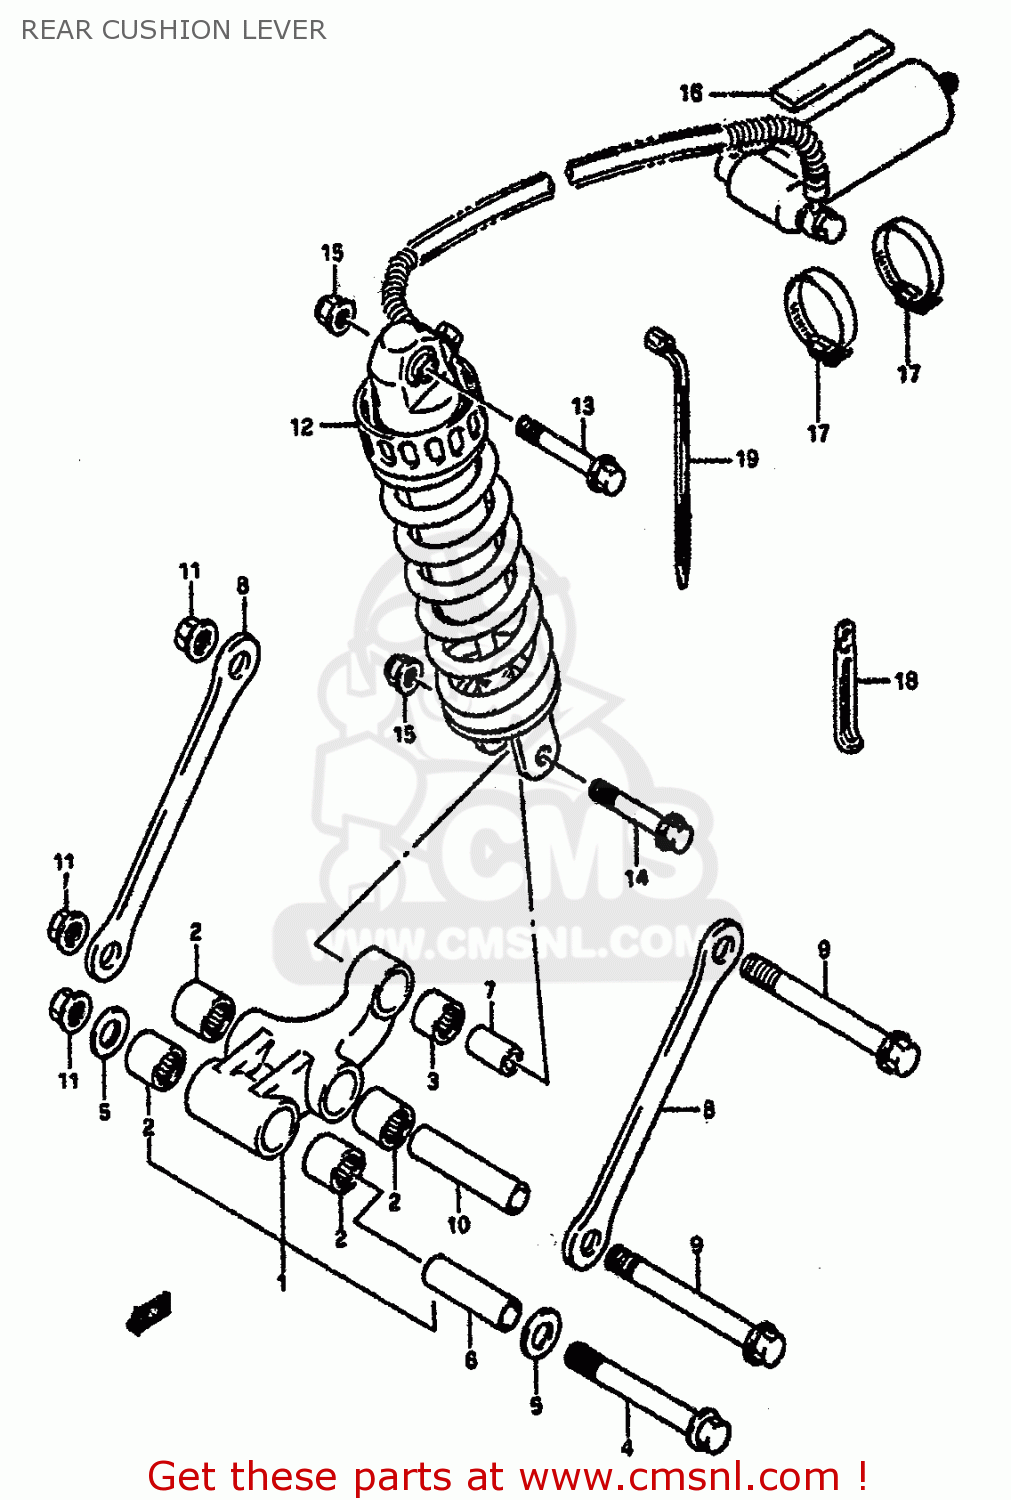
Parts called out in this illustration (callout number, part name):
1	LEVER SET,REAR CUSHION
2	BEARING(20X27X23.5)
3	BEARING(17X24X26)
4	SHAFT,RR CUSHION LEVER FR
5	WASHER
6	SPACER,RR CUSHION LEVER
7	SPACER,RR CUSHION LEVER
8	ROD,REAR CUSHION LEVER
9	SHAFT,RR CUSHION ROD
10	SPACER,RR CUSHION ROD
11	NUT
12	ABSORBER ASSEMBLY,REAR SHOCK
13	BOLT
14	BOLT(10X60)
15	NUT
16	CUSHION,RESERVOIR TANK
17	CLAMP
18	CLAMP
19	CLAMP(L:165)
